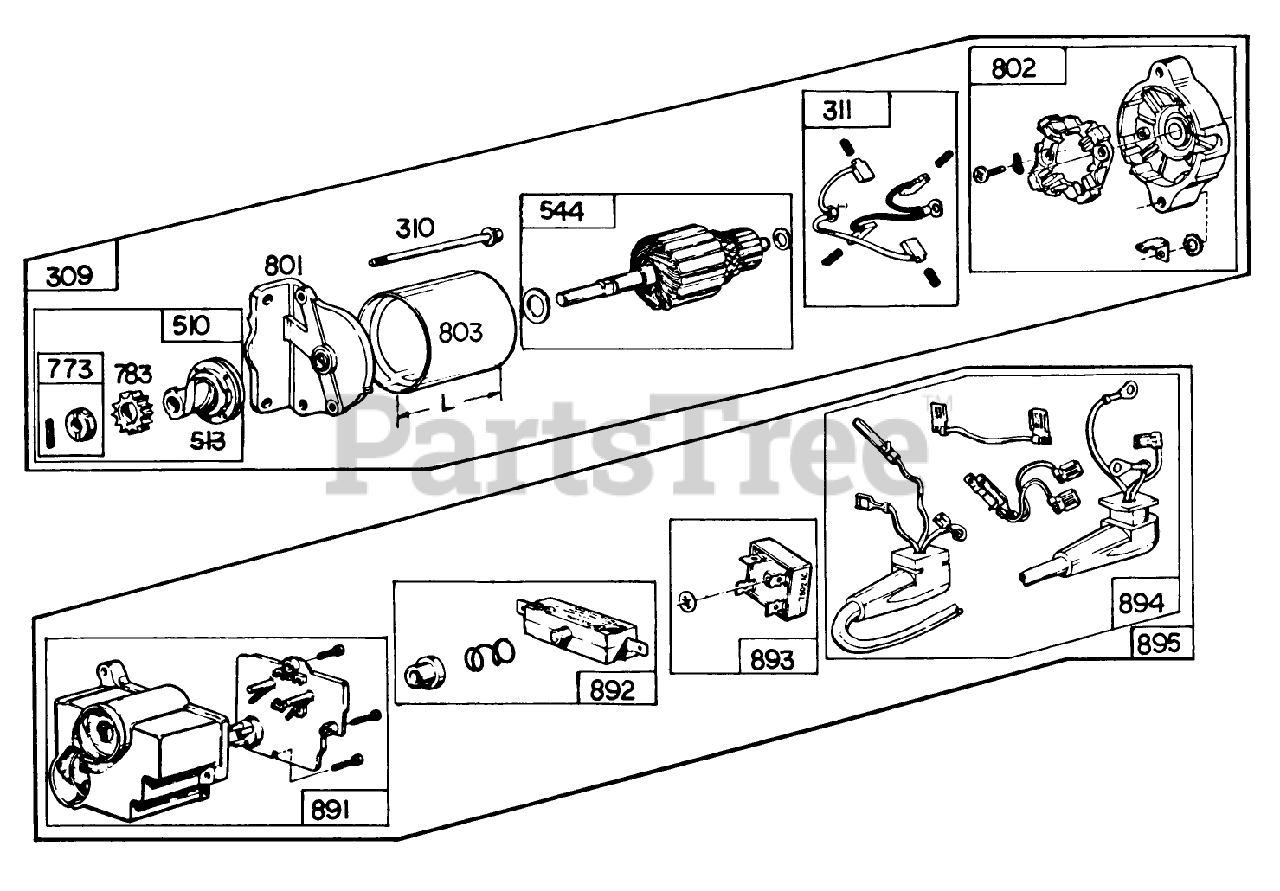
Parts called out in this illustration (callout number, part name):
309	Motor Drive Assembly
310	Thru Bolt Assembly
311	Brush Assembly
510	Drive Assembly
513	Clutch Assembly
544	Armature Assembly
773	Gear-Starter
801	Drive End Cap Assembly
802	Comm. End Cap Assembly
803	Housing Assembly
891	Housing Group
892	Switch Group
893	Rectifier
894	Lead Group
895	Control Group
